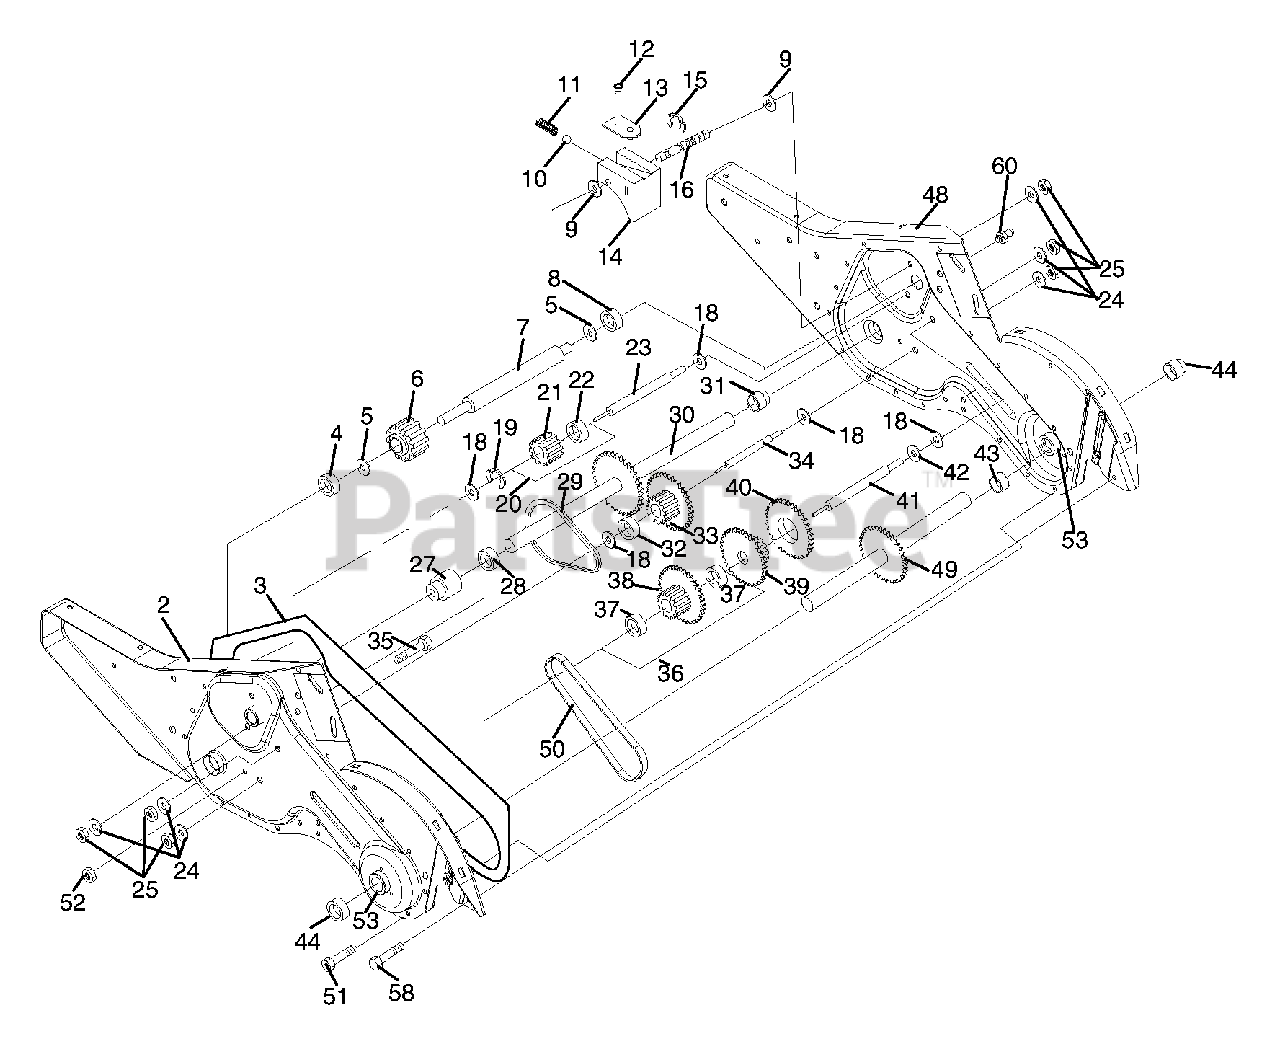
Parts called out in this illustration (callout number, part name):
1	Transmission Assembly
2	Gearcase, L.H. w/Bearing
3	Gasket, Gearcase
4	Bearing, Needle
5	Washer, Thrust 5/8 x 1.10 x 1/32
6	Pinion, Input
7	Shaft, Input
8	Bearing, Needle
9	Washer, Seal
10	Ball, Steel
11	Spring, Shift, Fork
12	O-Ring
13	Arm,. Shift
14	Fork, Shift
15	Ring, Klip
16	Shaft, Shift
18	Washer
19	Ring, Klip
20	Gear, Assembly, Reverse Idler
21	Gear, Reverse Idler
22	Bearing, Needle
23	Shaft, Reverse Idler
24	Washer, Lock 7/16
25	Nut, Hex 7/16-20
27	Bearing, Shaft, Ground Drive
28	Spacer 0.765 x 1.125 x 1.23
29	Chain #35-50 Pitch
30	Ground Shaft Assembly
31	Bearing, Shaft, Ground Drive
32	Spacer 0.70 x 1.00 x 1.150
33	Sprocket and Gear Assembly
34	Shaft, Reduction (2nd)
35	Screw, Whiz, Lock 5/16-18 x 3-1/2
36	Sprocket Assembly w/Bearing
37	Bearing, Needle
38	Sprocket, Tine
39	Gear, Cluster, Red 1st & 2nd
40	Gear, Reverse
41	Shaft, Reduction (1st)
42	Washer, Thrust
43	Spacer 1.01 x 1.75 x 0.760
44	Seal Asm, Oil
48	Gearcase, R.H. w/Bearing
49	Shaft, Tine
50	Chain, Roller #50-50 Pitch
51	Screw 1/4-20 x 1/2
52	Nut, Hex 5/16-18
53	Kit, Bearing, Tine Shaft
58	Bolt Shoulder 1/4-20 x 7/8
60	Fitting Grease
